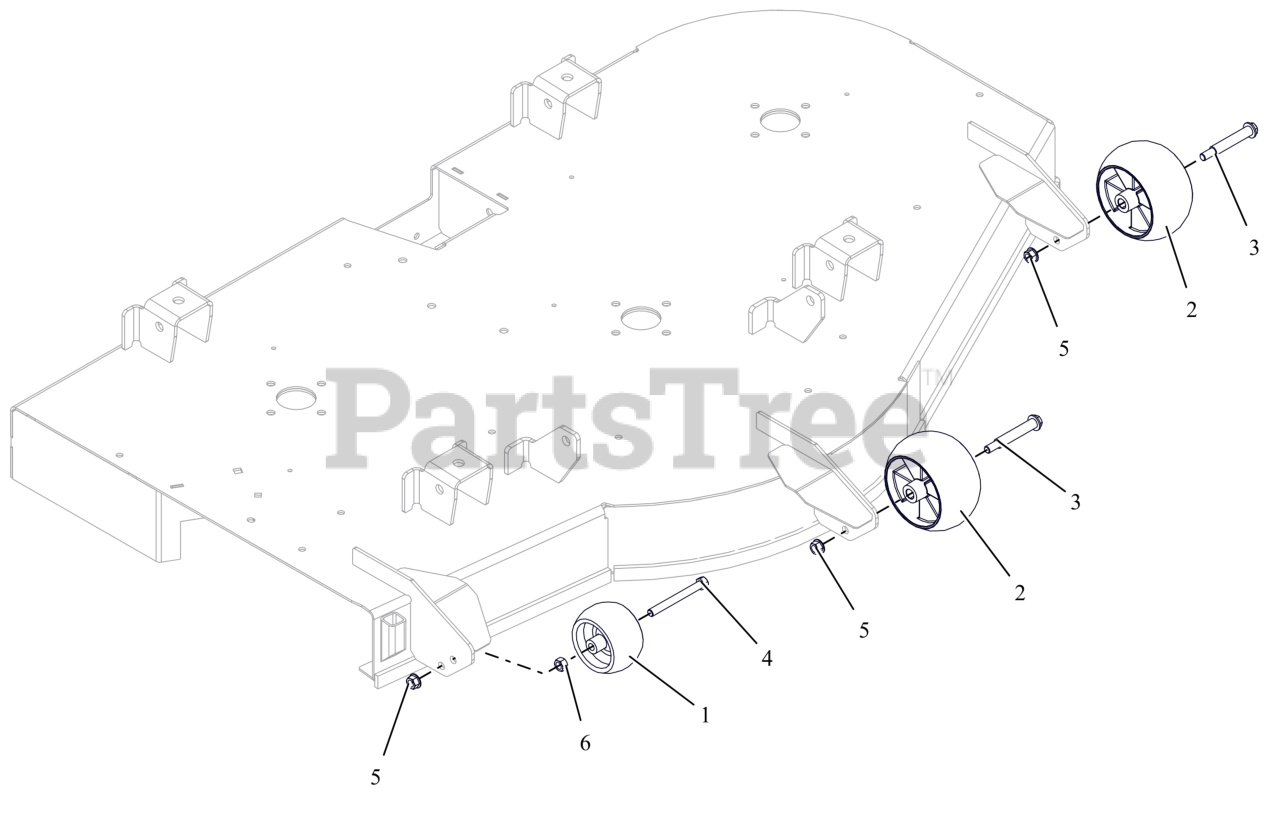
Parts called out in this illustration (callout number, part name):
2	ANTI-SCALP WHEEL - 5X OS
3	BLT-SHLDR .38-16X2.50 HWH G5
4	BLT, HEX .38-16X3.50 G5 ZCC
5	NUT-LK-CTR-FLG .375-16 GF ZCC
6	NUT-STD .375-16 G2 ZCC
